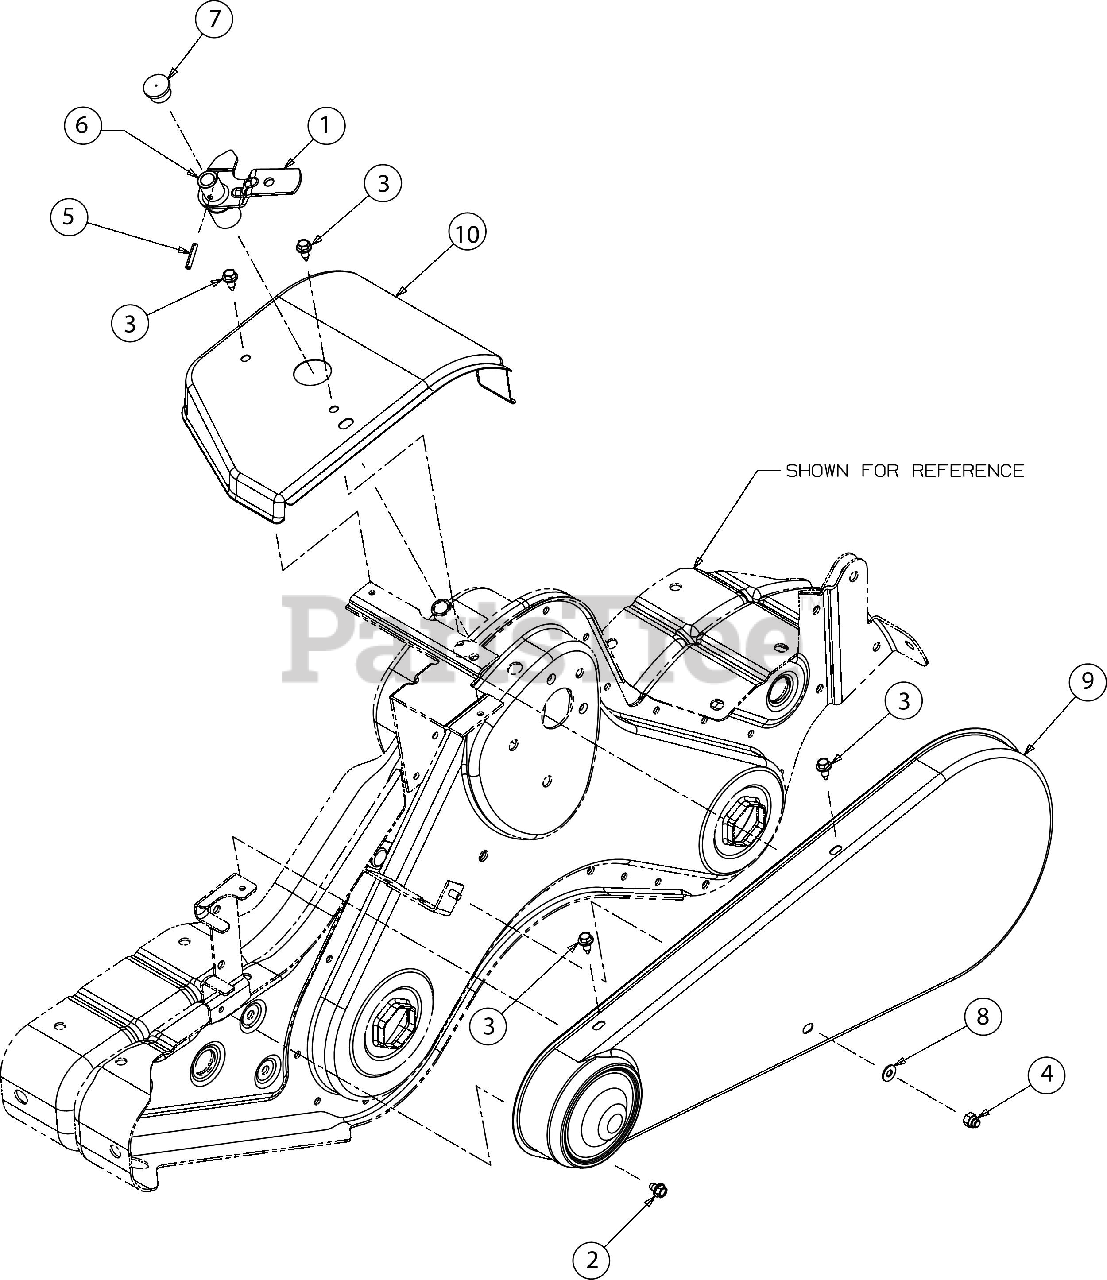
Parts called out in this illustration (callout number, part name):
1	SHIFT CRANK ASSEMBLY
2	SCREW 1/4-20 X .375
3	SCREW 1/4-20X.625
5	SPRING PIN 3/16 X 1.00
7	SHIFT CRANK CAP
8	FLAT WASHER .271:.630:.065
9	BELT COVER
10	SHIFT COVER
